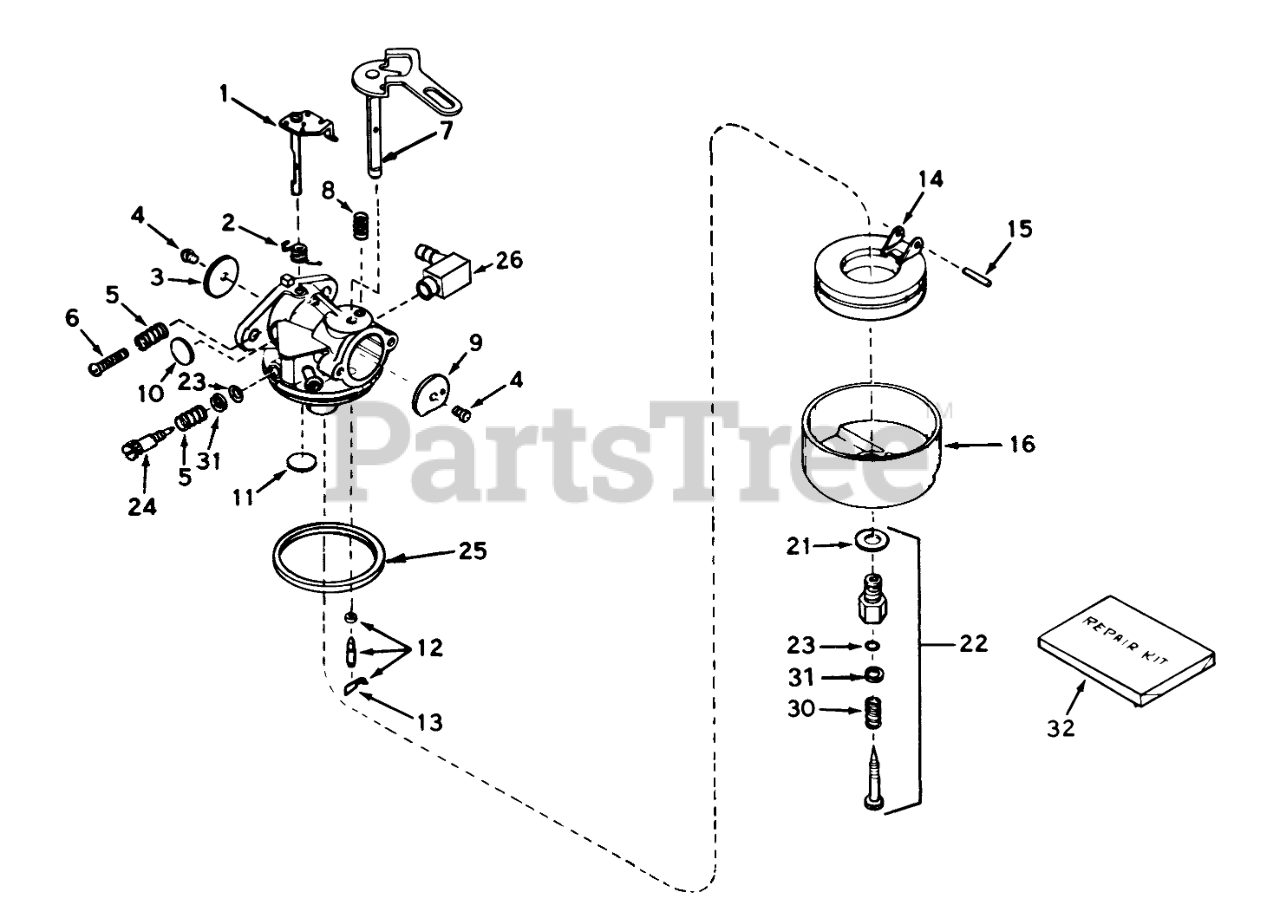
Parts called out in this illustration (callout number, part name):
1	Throttle Shaft and Lever ASM
2	Spring, Return
3	Shutter-Throttle
4	Screw-Shutter
5	Spring-Tension
6	Screw-Throttle Crack Screw / Idle Speed
7	Choke Shaft and Lever Asm
8	Spring-Positioning, Choke
9	Shutter-choke
10	Plug-Welch, Idle Mixture Well
11	Plug-Welch, Atmospheric Vent
12	Inlet Needle, Seat & Clip Assy. (Incl. Ref. #13)
13	Clip-Spring
14	Float
15	Shaft-Float
16	Bowl-Float (no drain)
21	Washer-Bowl Nut
22	Adjustment Screw Assy., Main (Incl. Ref. #21, 23, 30 & 31)
23	"O"Ring
24	Screw, Idle Adj.
25	O Ring-Bowl, Float
26	Fitting-Fuel
32	Kit-Repair
